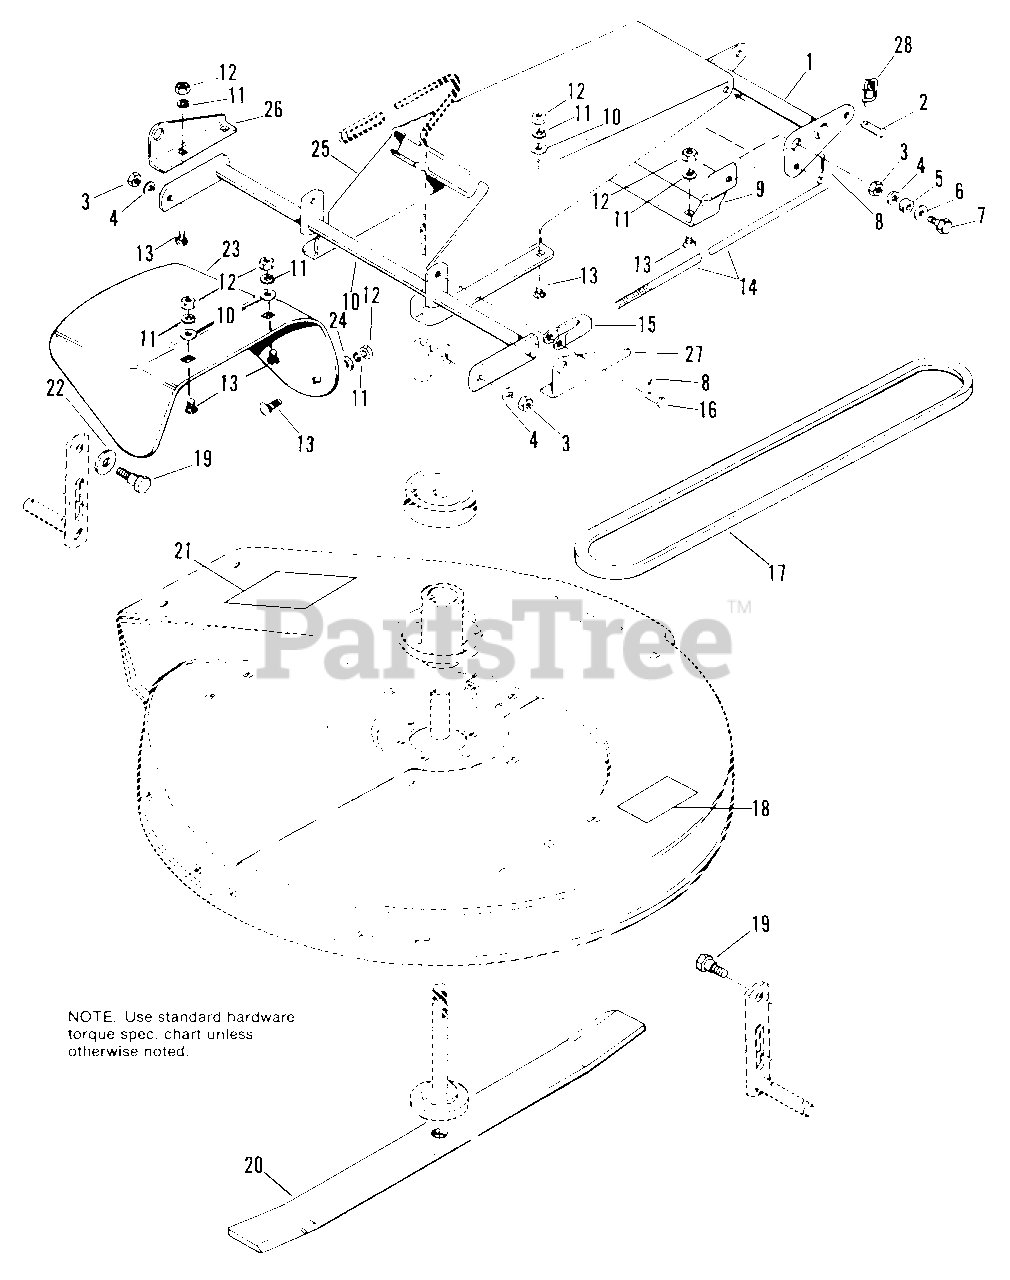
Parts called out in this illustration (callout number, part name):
1	BELLCRANK ASSY.
3	NUT, Hex, Full, 3/8-16
4	LOCKWASHER, 3/8
6	WASHER, Plain, 3/8
7	CAPSCREW, Hex Hd., 3/8-16 x 1
8	PIN, Cotter, 3/32 x 1
10	WASHER, Plain, 5/16
11	LOCKWASHER, 5/16
12	NUT, Hex, Full, 5/16-18
13	BOLT, Carriage, 5/16-18 x 5/8
14	ROD, Height Adjusting
15	CLEVIS, Adjusting
16	PIN, Yoke, 3/8
18	DECAL, Danger
19	BOLT, Shoulder, 3/8-16 X 1.34
20	BLADE, Mower
21	DECAL, Danger
22	WASHER, Plain, 7/16
23	DEFLECTOR
24	LEVER ASSY.
25	COVER, Belt
26	BRACKET, Pivot, L.H.
27	BRACKET, Pivot, R.H.
28	PIN, Safety
